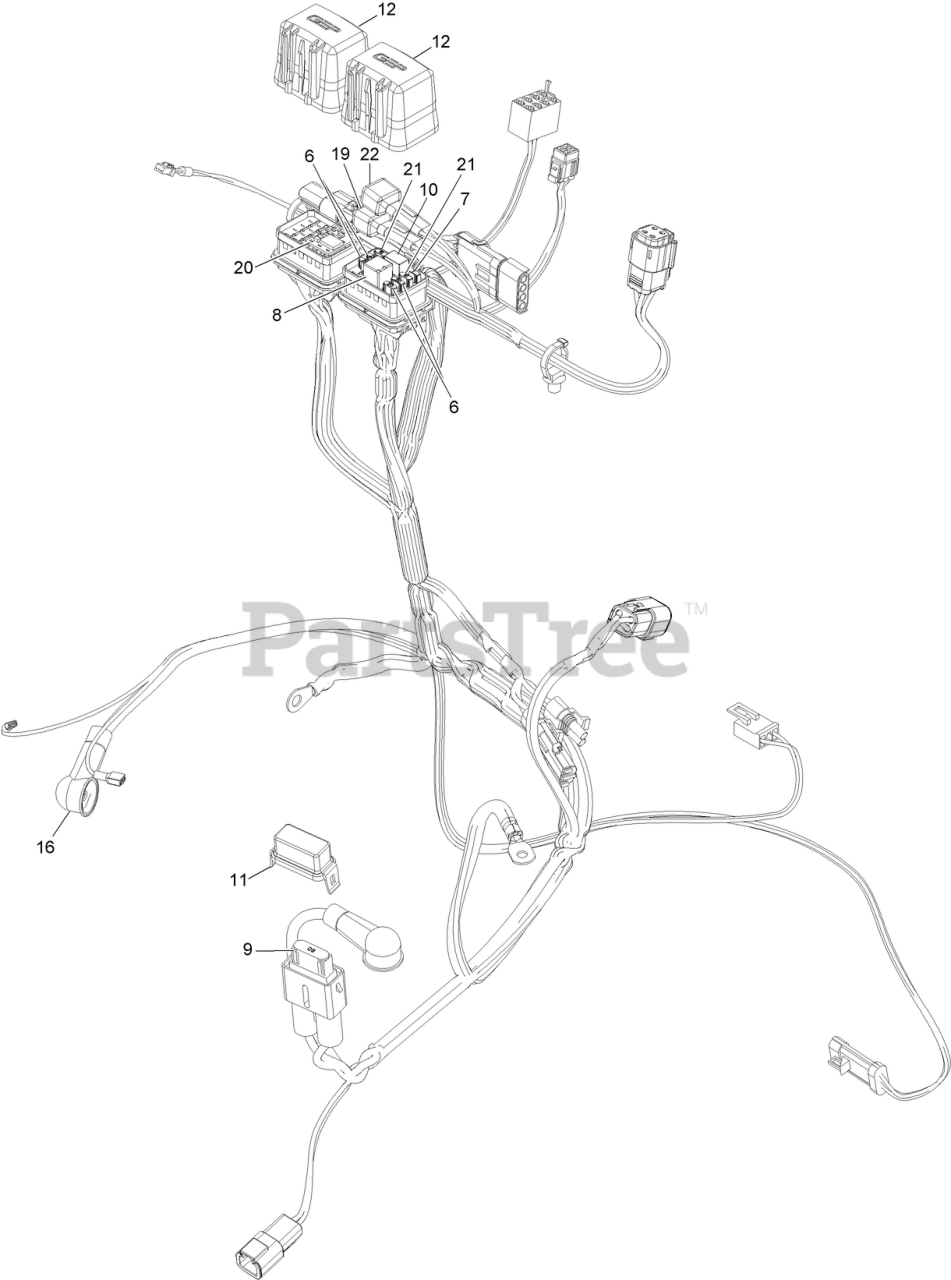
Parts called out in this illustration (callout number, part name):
6	FUSE-MINI BLADE, 20 AMP
7	Fuse-Mini Blade, 1 Amp
8	RELAY-MICRO
9	FUSE-MAXI, 60 AMP
10	Relay-Coil, NC, Mp280
11	Cover-Fuse Holder, Maxi
12	Cover-Fuseblock, 24F, Gep
16	Insulator-Lug, Red
20	PCA-HIGH POWER SSR
21	FUSE-MINI BLADE, 15 AMP
